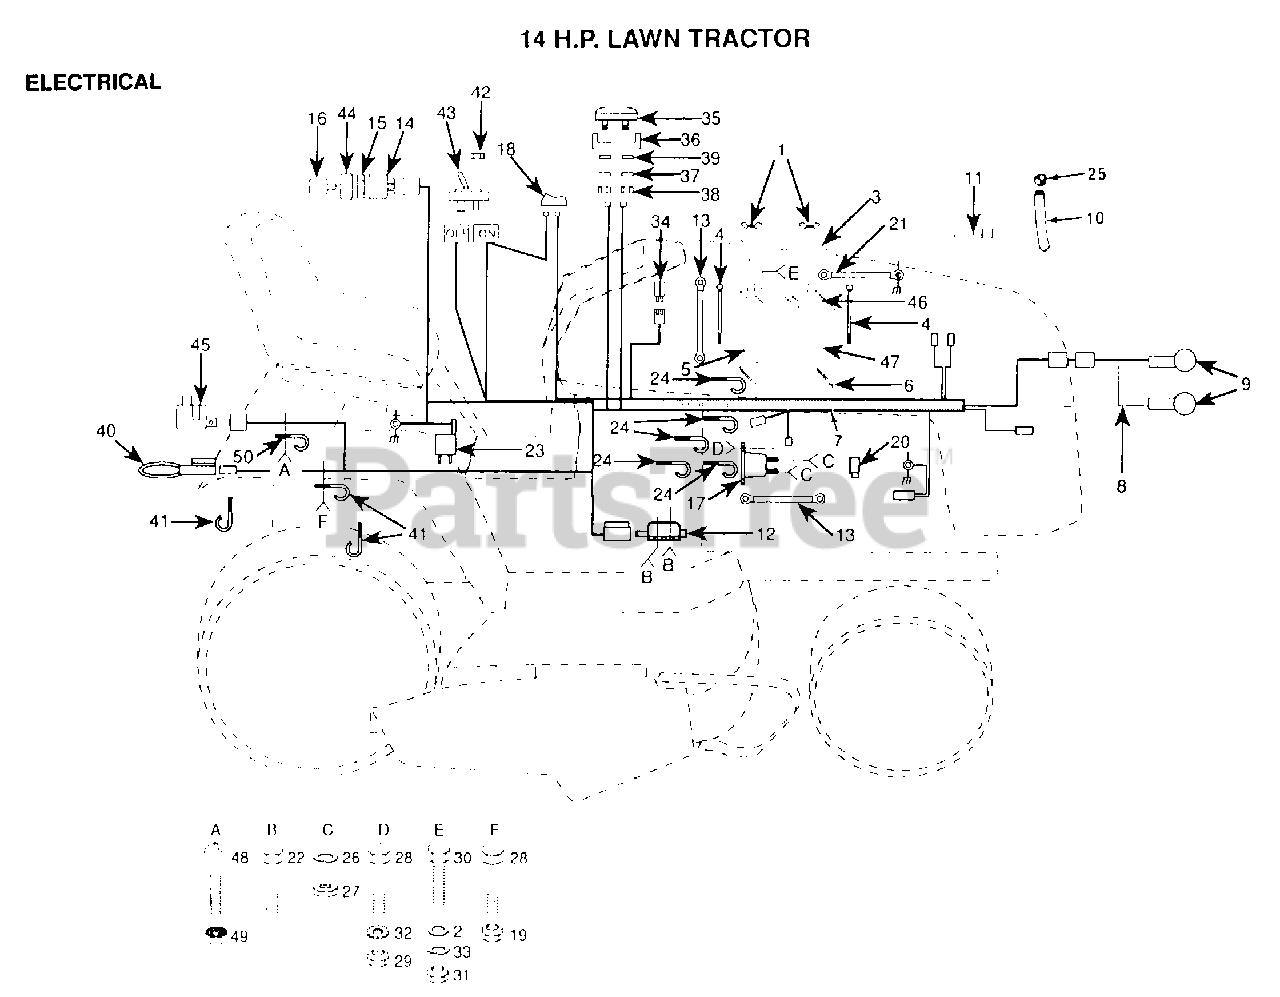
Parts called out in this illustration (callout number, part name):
2	WASHER
4	BOLT
6	"TRAY T, BATTERY"
7	HARNESS IGN ITION
11	WIRE TIE
12	SWITCH INTERLOCKT
13	CABLE-BATTERY T
16	KEY
18	SWITCH LT
21	CABLE T
22	SCREW
23	RELAY ASSY T
24	CLIP T
25	HOSE CLAMP T
27	NUT
28	BOLT
29	NUT
30	BOLT LT
33	LOCKWASHER
34	FUSE HYT
35	AMMETER T
39	WASHER
41	CLIPT
42	HEX NUT T
43	SWITCH.PTO.T
45	SWITCH SEAT
46	"CAP,BATTERY "
47	DECAL
49	"NUT,KEPS"
